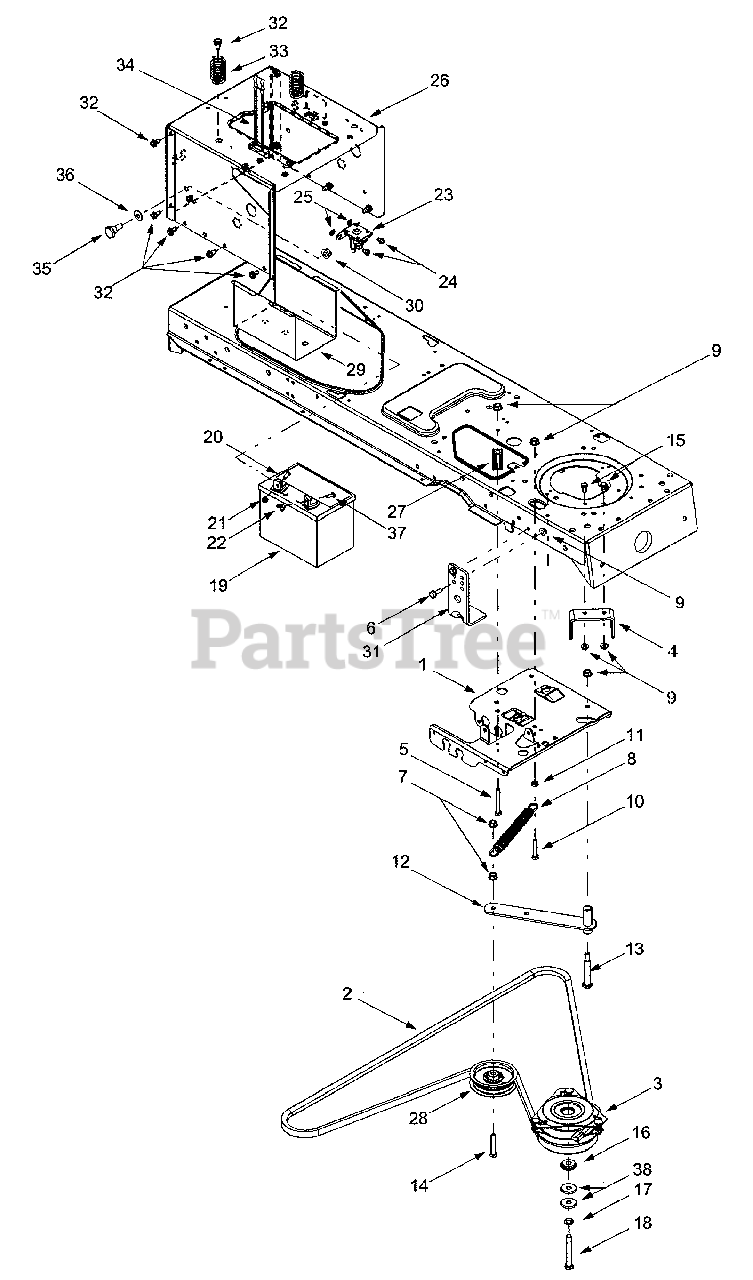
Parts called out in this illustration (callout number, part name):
2	PTO Belt
3	Electric PTO Clutch
6	Hex Head Washer Screw, 5/16-18 x .875
7	Flange Lock Nut, 3/8-16
8	Extension Spring, .62 x 5.62
9	Flange Lock Nut, 5/16-18
10	Hex Cap Screw, 5/16-18 x 1.75
11	Hex Nut, 5/16-18
12	Idler Bracket Assembly
13	Shoulder Screw, 1/2 x 2.5
14	Hex Cap Screw, 3/8-16 x 2.0
15	Hex Cap Screw, 5/16-18 x .625
16	Shoulder Spacer, 1.38 x .445 x .36
17	Lock Washer, 7/16
18	Hex Cap Screw, 7/16-20 x 3.25 (Grade 5)
19	12-volt Battery, 270 CCA
20	Hex Cap Screw, 1/4-20 x .62
21	Hex Sems Nut, 1/4-20
22	Wing Nut, 1/4-20
23	Solenoid, 12-Volt, 100 Amp
24	Self Tapping Screw, 1/4-20 x.5
25	Lock Washer, 1/4
28	Idler Pulley, 3.5
32	Self Tapping Screw, 5/16-18 x .625
33	Compression Spring, 1.28 x 3.5
34	Battery Strap
35	Shoulder Screw, .625 x .5, 7/16-20
36	Bell Washer, .45 x 1.0 x .062
37	Shoulder Screw, 1/4-20, .25 x .15
38	Flat Washer, .45 x 1.25 x .164
